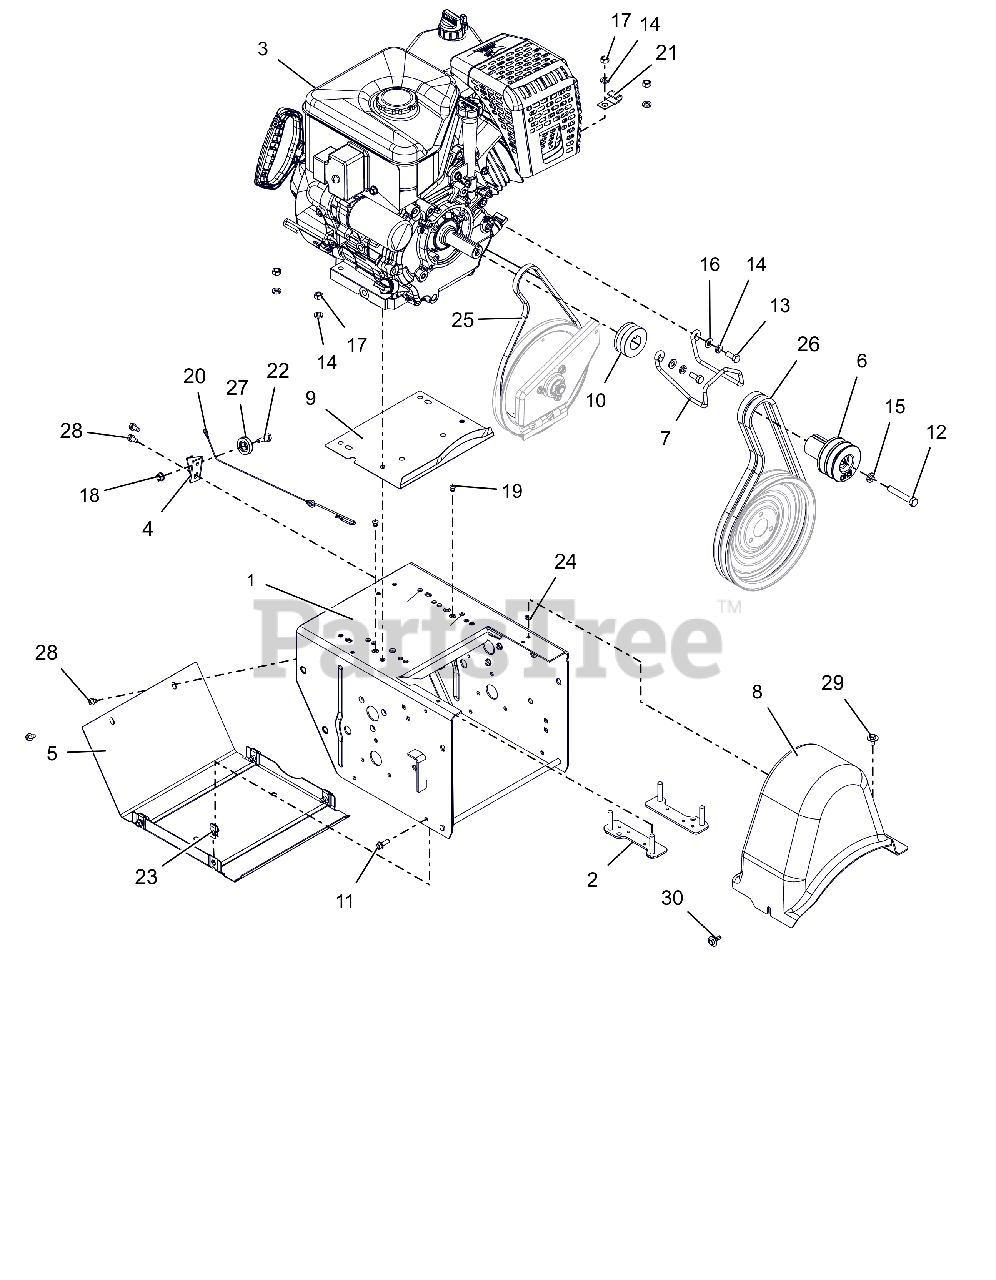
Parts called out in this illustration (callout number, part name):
1	FRAME, MAIN-DELUXE(WELDMENT)
2	STRAP, BOLT-LARGE
3	ENGINE, AX414 GEN 3 120V/60W
4	BRACKET, CABLE PULLEY
5	COVER, BOTTOM
6	SHEAVE,ATTACHMENT-SHO 2 GRV
7	FINGER, BELT
8	COVER, BELT-LARGE
9	BAFFLE, WATER - LARGE BLOCK
10	SHEAVE, DRIVE
11	BLT-HEX .25-20X.75 HWH YZ GR5
12	BLT-HEX .38-24X2.25 YWZC GR5
13	BLT-HEX .31-24X.75 YWZC GR5
14	WSHR-LK .312X.097 HVY YWZC
15	@WSHR-LK .38X.094 REG YWZC
16	@WSHR-FL-STL.344X.688X.065YWZC
17	@NUT-HEX .31-18 YWZC
18	@NUT-LK-TOP-FLG .25-20 YWZC
19	RVT-POP .187 YZ
20	CABLE, LOWER TRACTION,SS & PRO
21	J-CLAMP
22	BOLT, SHLDR-.375X.375X.25-20
23	NUT-RTNR .25-20X.56
24	NUT-PUSH .25X.50 O.D.
25	V-BELT, 3L-WRAPPED
26	V-BELT, HA-RAW EDGE (SET)
27	PULLEY, CABLE
28	SCR-TAP .25-20X.50 HWH TR YWZ
29	SCR-TAP .25-20X.50 LGHWH TR YZ
30	SCR-TAP .25-20X.5 CAPTIVE
